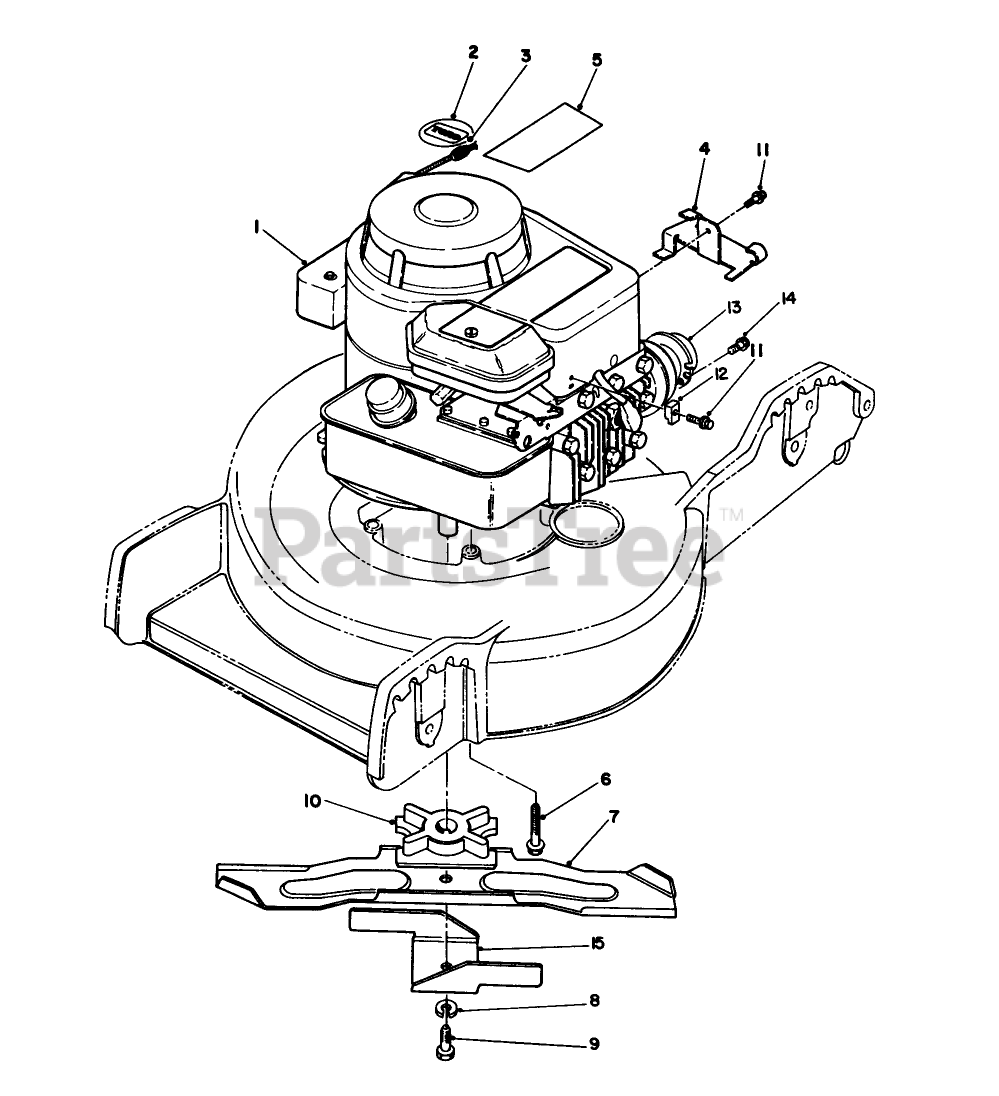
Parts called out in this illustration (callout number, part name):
1	Engine
3	STOP-ROPE
4	CABLE BRACKET *
8	WASHER-LOCK
9	SCREW-HH
10	BLADE RETAINER
11	CLAMP SCREW F/W ENGINE
12	CASING CLAMP F/W ENGINE
15	18 ACCELERATOR *
